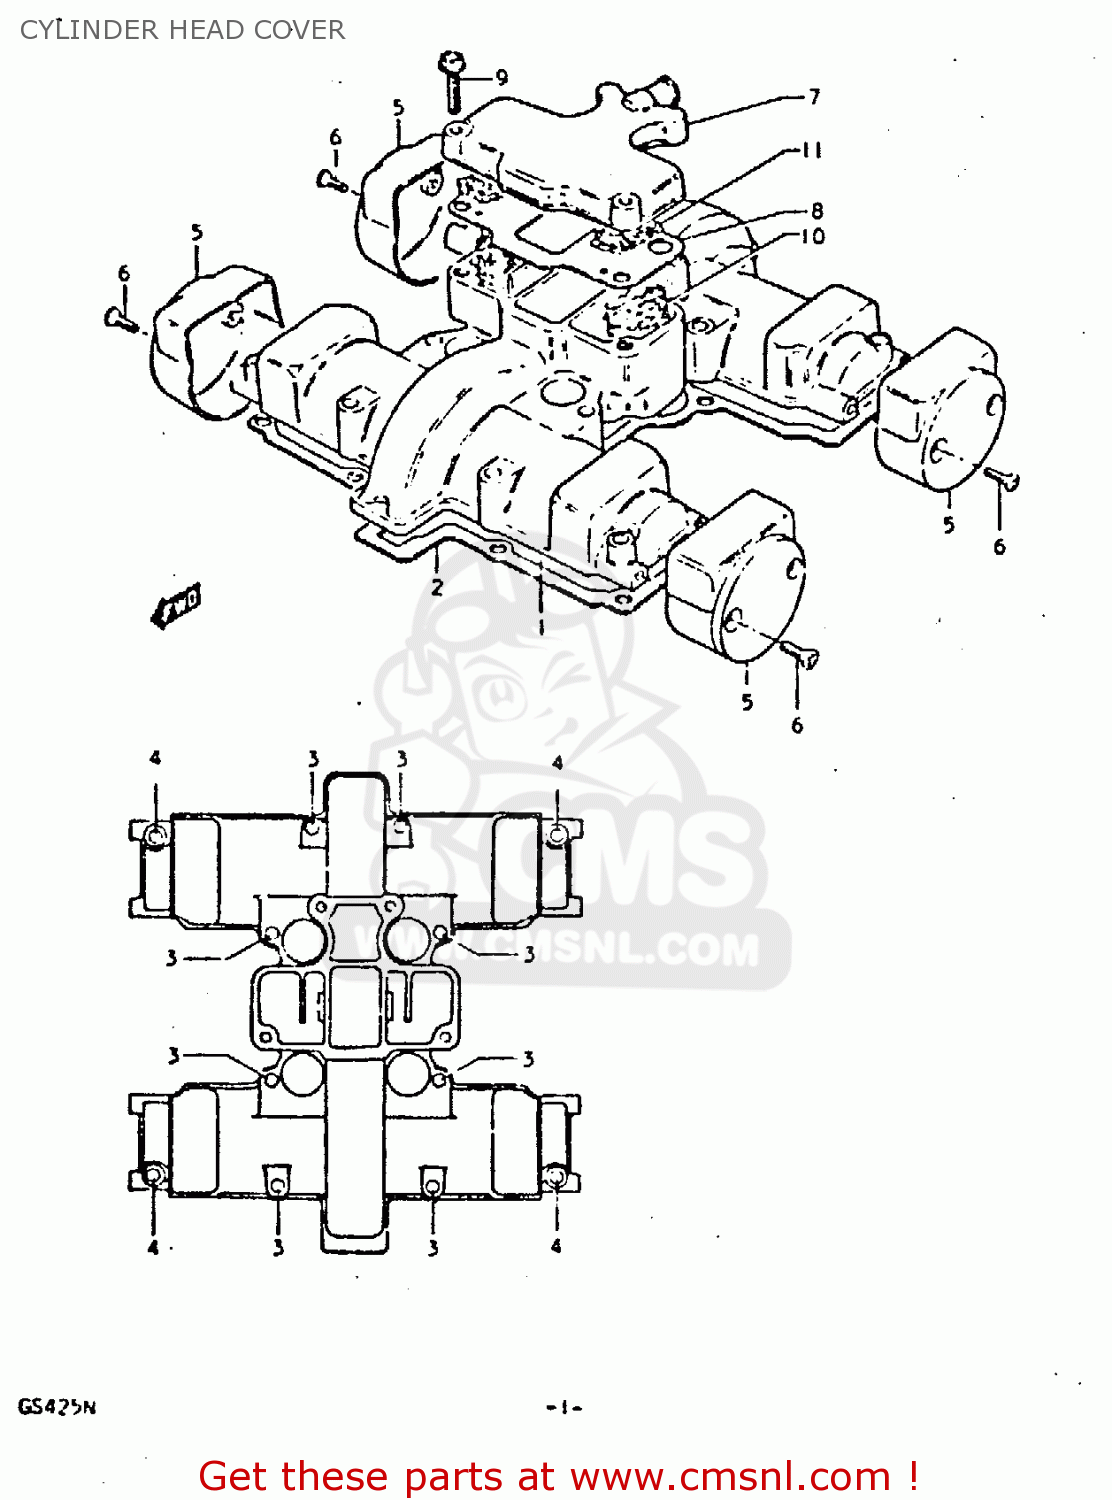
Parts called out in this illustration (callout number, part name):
1	COVER,CYLINDER HEAD
2	GASKET,CYLINDER HEAD COVER (MCA)
3	BOLT
4	BOLT
5	CAP,CYLINDER HEAD COVER
6	SCREW
7	COVER,BREATHER
8	GASKET (MCA)
9	BOLT
10	COVER,BREATHER
11	SEPARATOR,OIL BREATHER
